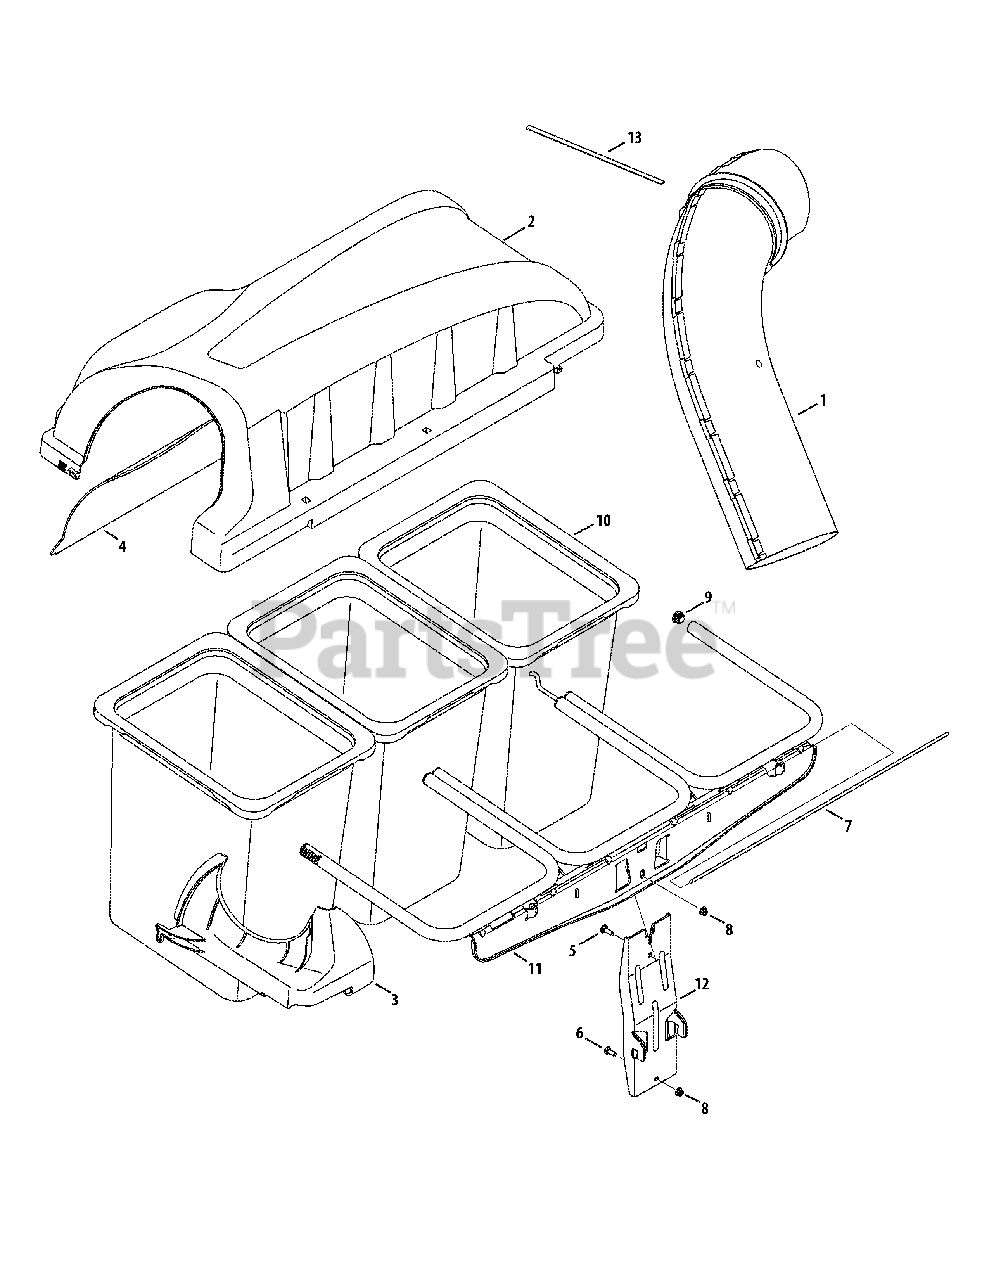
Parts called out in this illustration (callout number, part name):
1	Upper Chute Assembly
2	Triple Bagger Cover Assembly
3	Upper Chute Support
4	Bagger Cover Screen
5	Carriage Screw, 5/16-18 x 1.00"
6	Hex Head Screw, 5/16-18 x .75"
7	Cover Hinge Pin
8	Flange Lock Nut, 5/16-18
10	Grass-bag Assembly
13	Adhesive Strip
